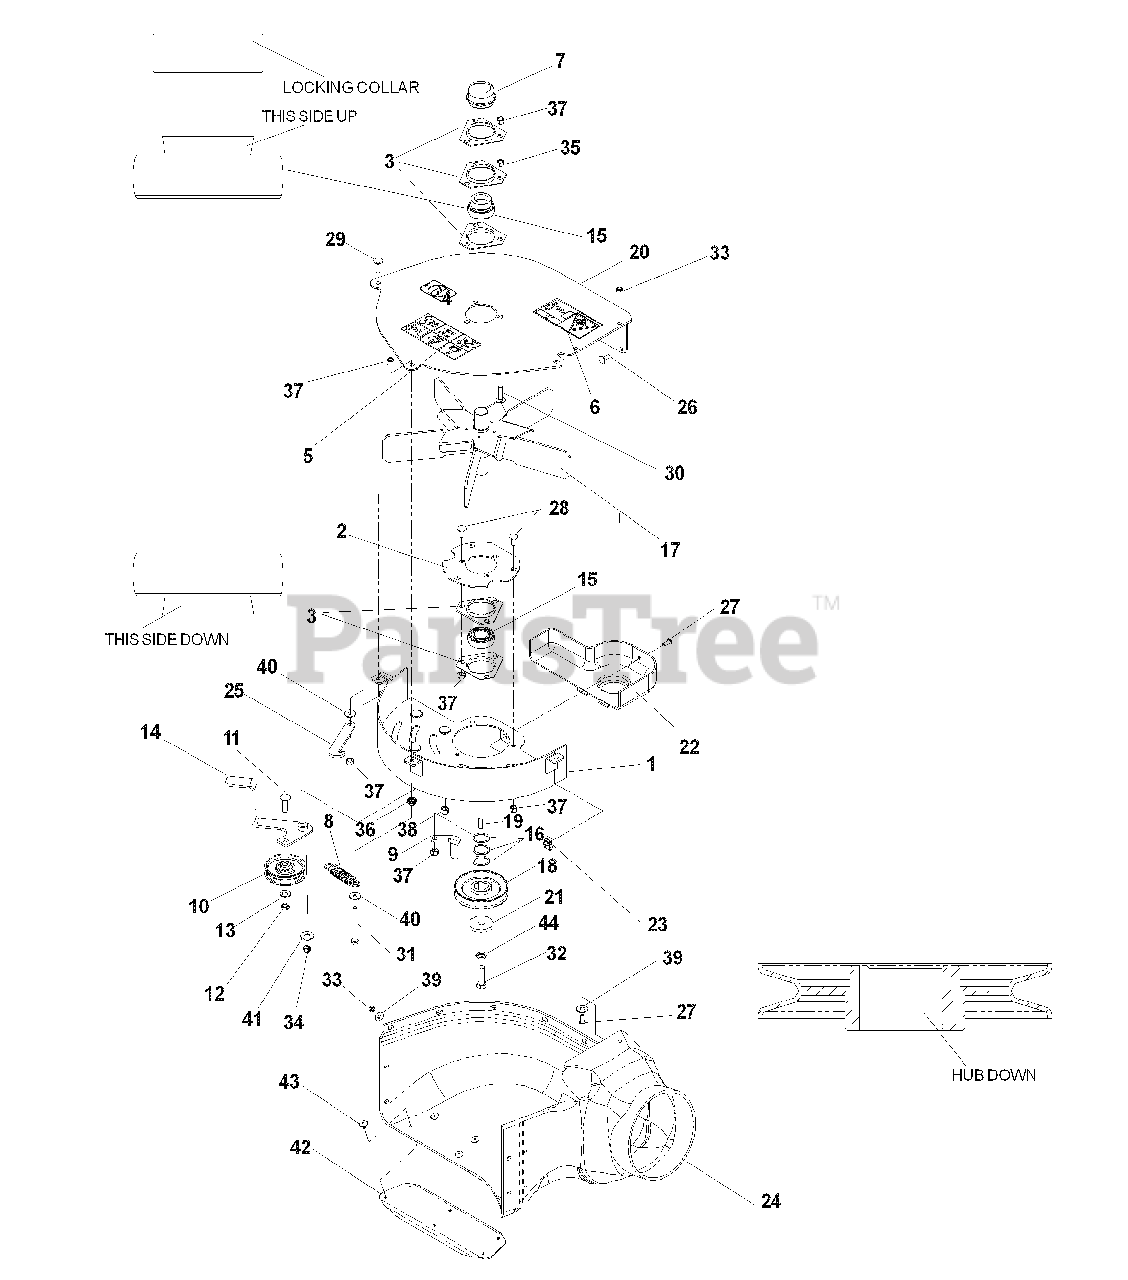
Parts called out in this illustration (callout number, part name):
1	FLOOR WELDMENT
2	BEARING PLATE
4	DECAL, NO STEP
5	DECAL, WARNING
6	DECAL, SEVERING
7	GREASE CAP
9	BELT GUIDE
11	RHSNB, 3/8-16x1 1/4
12	NUT, 3/8-16, JAM NYLOC
13	WASHER, 3/8, SAE
16	BUSHING, MACHINE, 18 GA
17	FAN WELDMENT
18	SHEAVE, 4"
19	KEY, 1/4" SQ. x 3/4"
21	WASHER, HEAVY
22	PULLEY SHIELD
23	RETAINER, 1/4C, "U" TYPE
24	BLOWER HOUSING
25	KEEPER, IDLER
26	RHSNB, 1/4-20x3/4, GR2
27	SCREW, 1/4-20x5/8, BTN
28	RHSNB, 5/16x3/4
29	RHSNB, 5/16-18x1
30	RHSNB, 5/16Cx1 1/4
31	HCS, 5/16-18x2 3/4
32	HCS, 7/16-20x1 1/2
33	NUT, 1/4C, THIN NYLOC
34	NUT, 5/16C, CENTERLOCK
35	NUT, 5/16C
36	NUT, 5/16C
37	NUT, 5/16C, NYLOC
38	NUT, 3/8C, NYLOC
39	WASHER, 1/4
40	WASHER, 5/16
41	WASHER, 3/8
42	BLOWER SUPPORT
44	LOCKWASHER, 7/16
